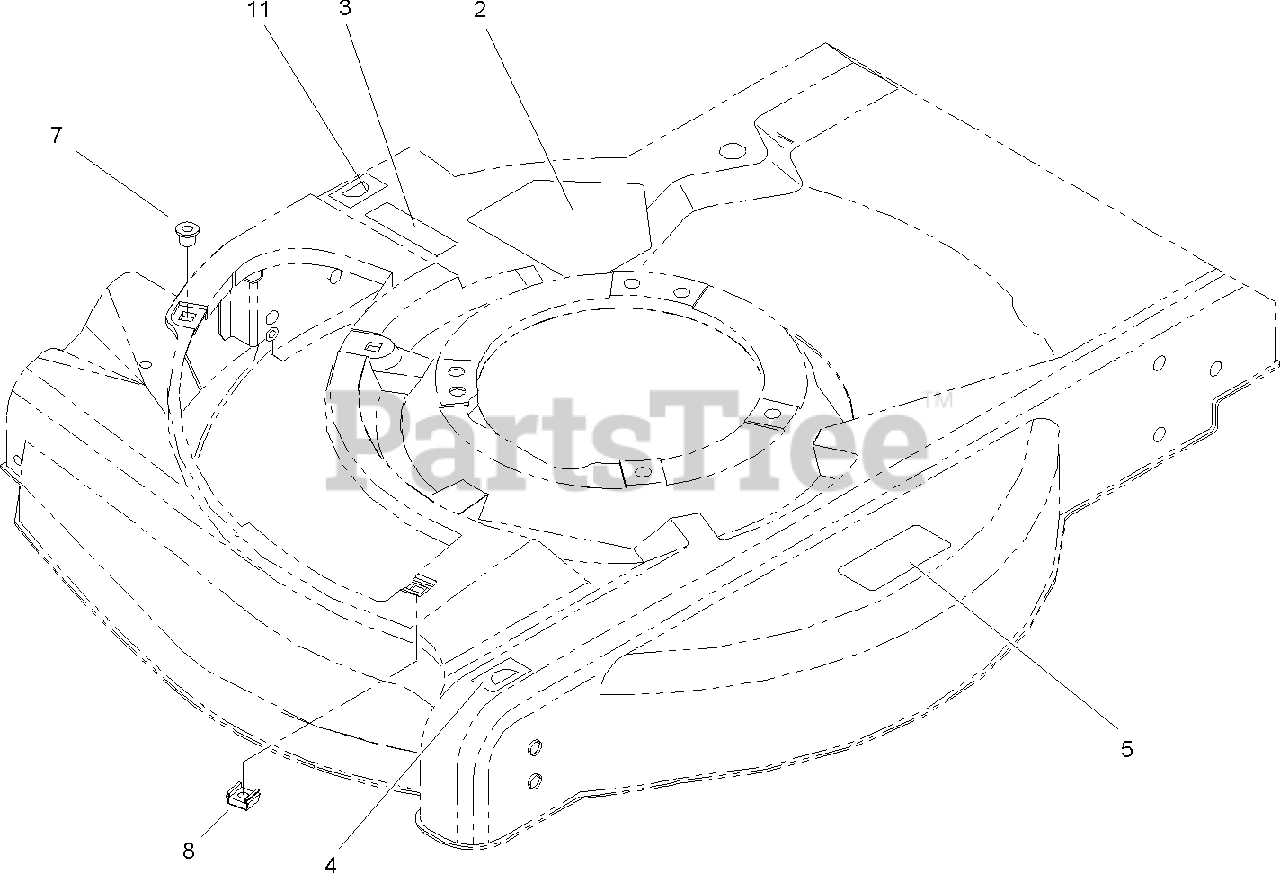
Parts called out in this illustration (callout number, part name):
2	DECAL-DANGER
3	DECAL-WARNING
4	DECAL-HOC, LH
5	DECAL-WARNING
7	NUT-CLIP
8	NUT-CAGE
11	DECAL-HOC, RH
